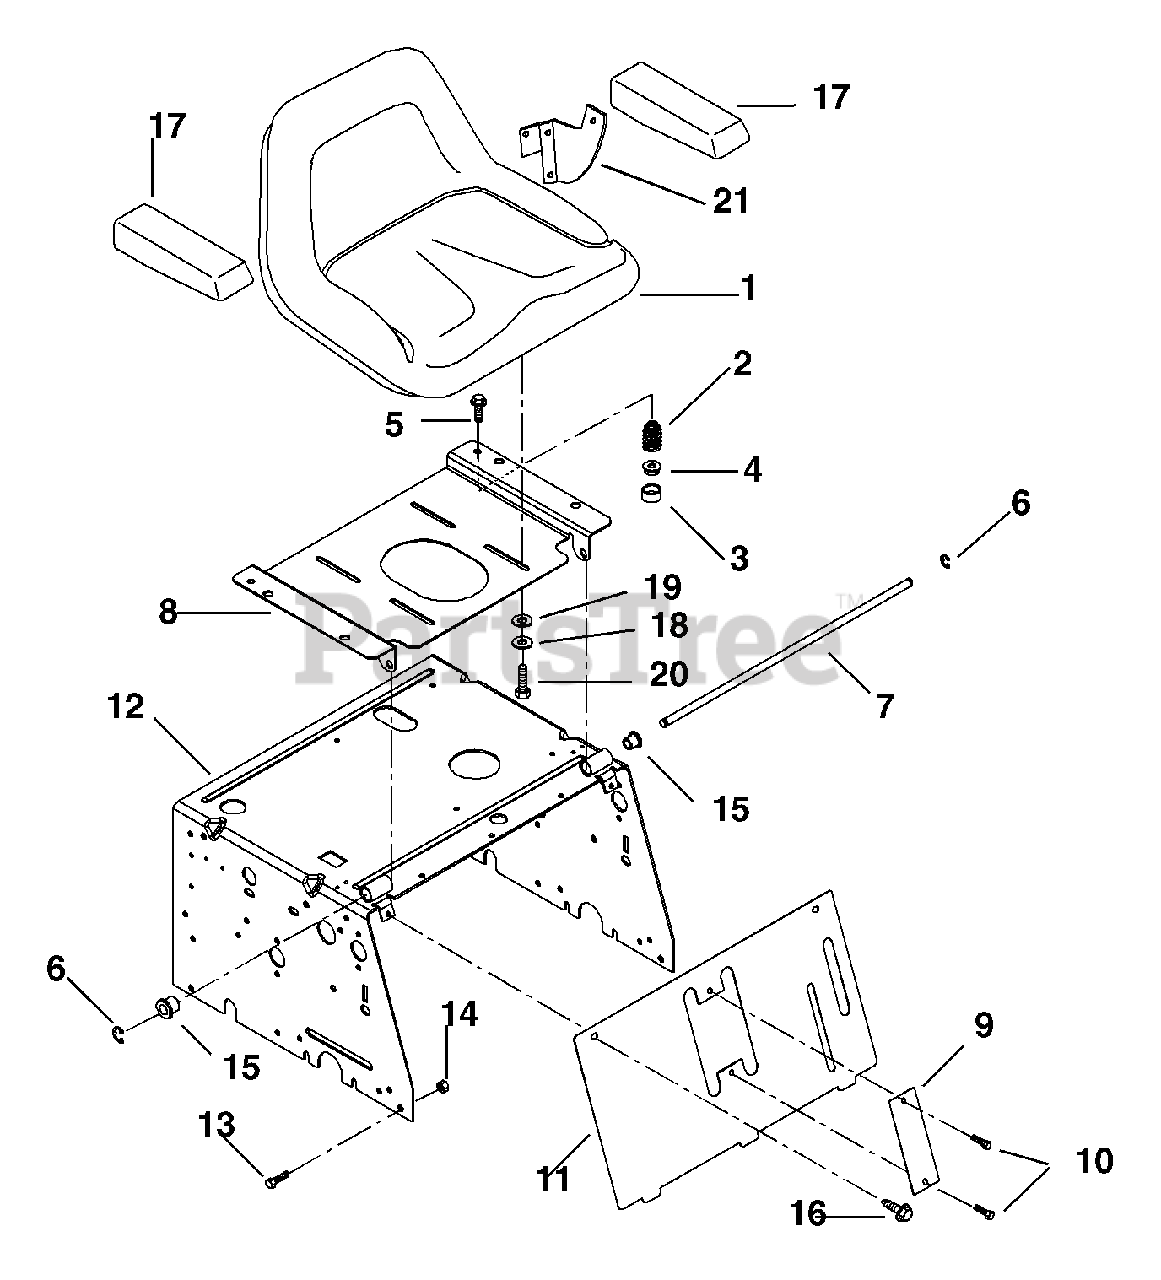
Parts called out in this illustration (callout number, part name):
2	Spring-Compression 2.9L x 2.02 OD
3	Boot-Seat Spring
4	Nut-Locking, Flange .375-16
5	Bolt-Hex Flanged Whiz Lock Head .38-16 x .75
6	Ring-Retaining-External .500 x .042
7	Axle-Front
8	Plate-Seat
10	Bolt-Hex .25-20 x .50 Grade 5
11	Panel-Weldment
12	Support-Seat Weldment
13	Bolt-Hex .38-16 x 1.00 Grade 5
14	Nut-Locking .375-16 Grade A
15	Bushing-Flange
16	Screw, Tapping .31-18 x .75
17	Arm Rest
18	Washer-Lock .31 x .078
19	Washer-Flat-Steel .344 x .688 x .065
20	Bolt-Hex .31-18 x 1.00 Grade 5
21	Bracket-Left Hand Armrest
21	Bracket-Right Hand Armrest
21	Hardware Pack, Armrest Kit
